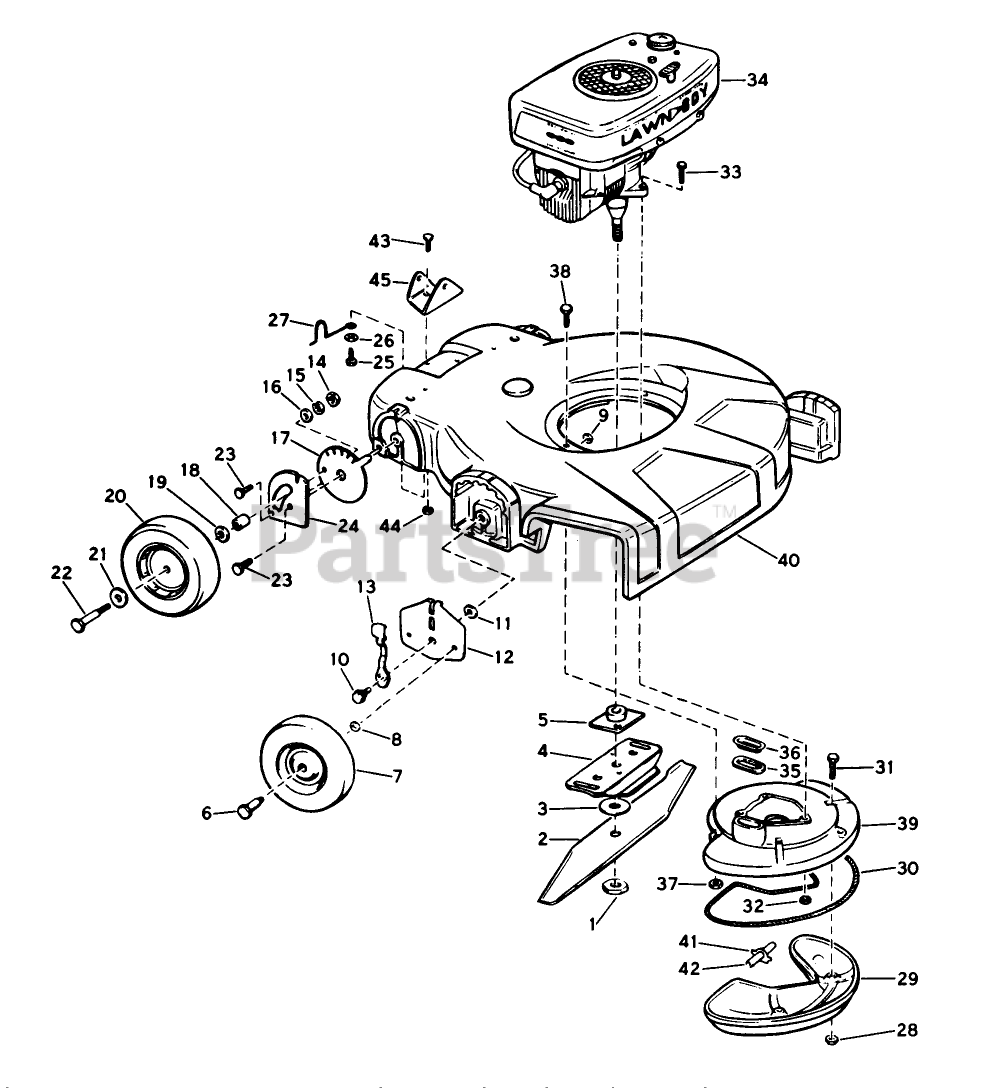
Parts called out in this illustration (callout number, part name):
1	NUT-BLADE
5	PLATE AND COLLAR ASM
6	BOLT WHEEL
8	WASHER WROUGHT
9	NUT
10	BOLT
14	Nut-Hex
15	WASHER, LOCK
17	Lever-Wheel
18	Spacer-Wheel
22	Bolt-Wheel
24	Plate-Wheel Height Adj.
26	WASHER
27	Spring-Wheel Height Adj.
28	LOCKNUT E
32	NUT
35	GASKET S
36	SLEEVE
37	NUT
41	Gasket-Internal Tube
42	Tube-Internal Muffler
43	Screw
44	STOP NUT
